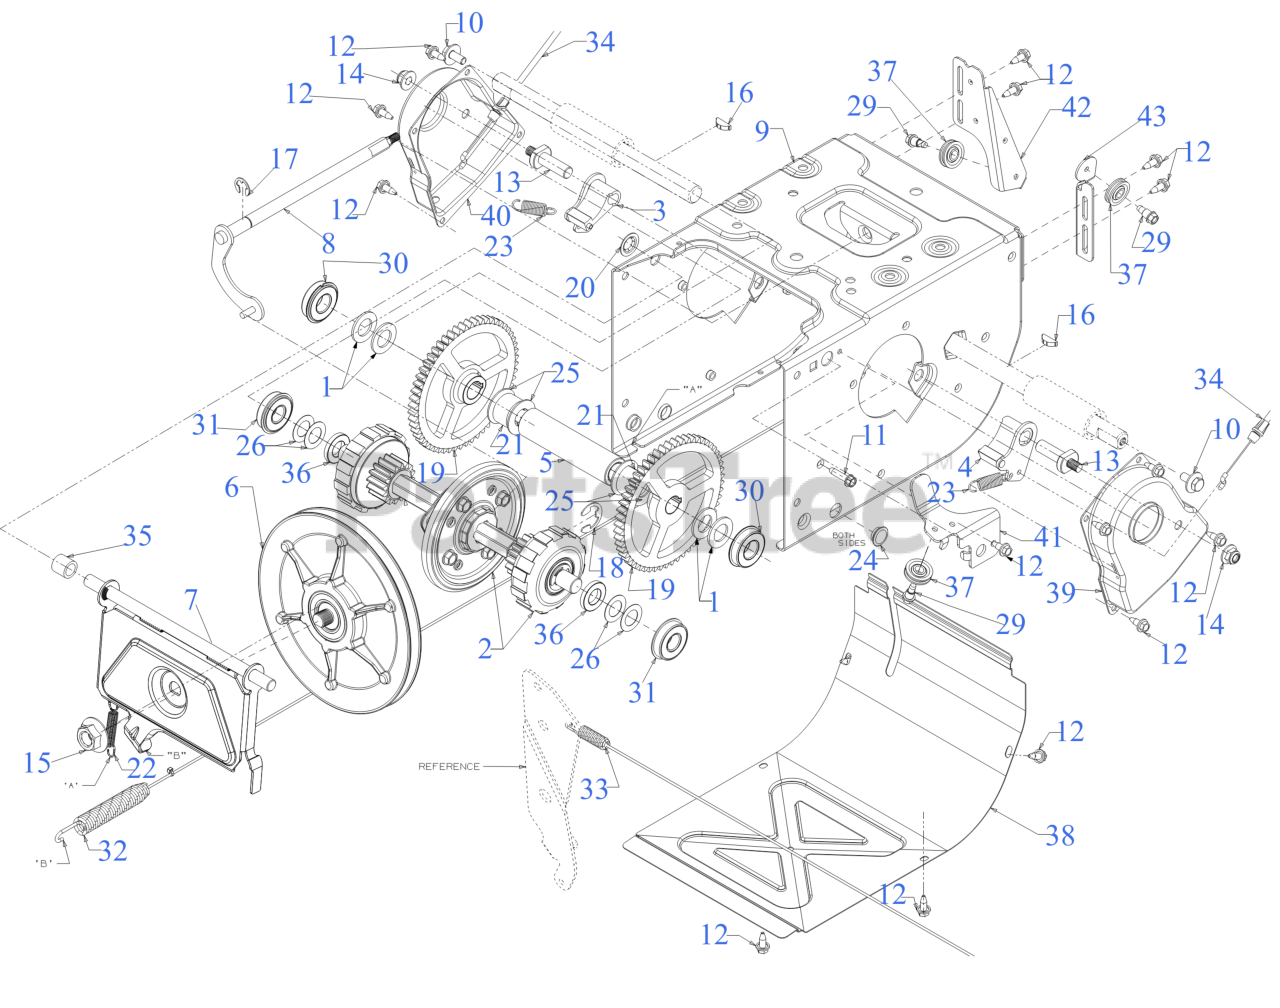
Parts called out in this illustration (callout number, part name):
1	WASHER .764X1.312X.091
2	PLANETARY FRICTION WHEEL HEX SHAFT
3	DOGG ASSEMBLY (RH)
4	DOGG ASSEMBLY (LH)
5	AXLE SUPPORT TUBE ASSEMBLY
6	FRICTION WHEEL DISC ASSEMBLY
8	SHIFT ROD ASSEMBLY
9	DRIVE FRAME
10	SCREW 5/16-24 x .750 GR5
11	SCREW 1/4-20 x 1.00
12	SCREW 1/4-20X.625
13	ACTUATOR SHAFT
15	FLANGE NUT 5/8-18
16	KEY 3/16 x 3/4
17	E-RING FOR .500 SHAFT
18	RETAINING RING
21	SPACER: .76ID x .75
22	EXTENSION SPRING
23	EXTENSION SPRING
25	FLAT WASHER
26	FLAT WASHER .67X 1.174X .02
29	SHOULDER SCREW
30	BALL BEARING
31	BALL BEARING W/RET
32	WHEEL DRIVE CABLE 44.955"
33	AUGER DRIVE CABLE 47.48"
34	STEERING CABLE
35	SPACER-.513 ID x .703 OD x .69
37	CABLE GUIDE ROLLER
42	CABLE GUIDE BRACKET (DRIVE)
43	CABLE GUIDE BRACKET (AUGER)
